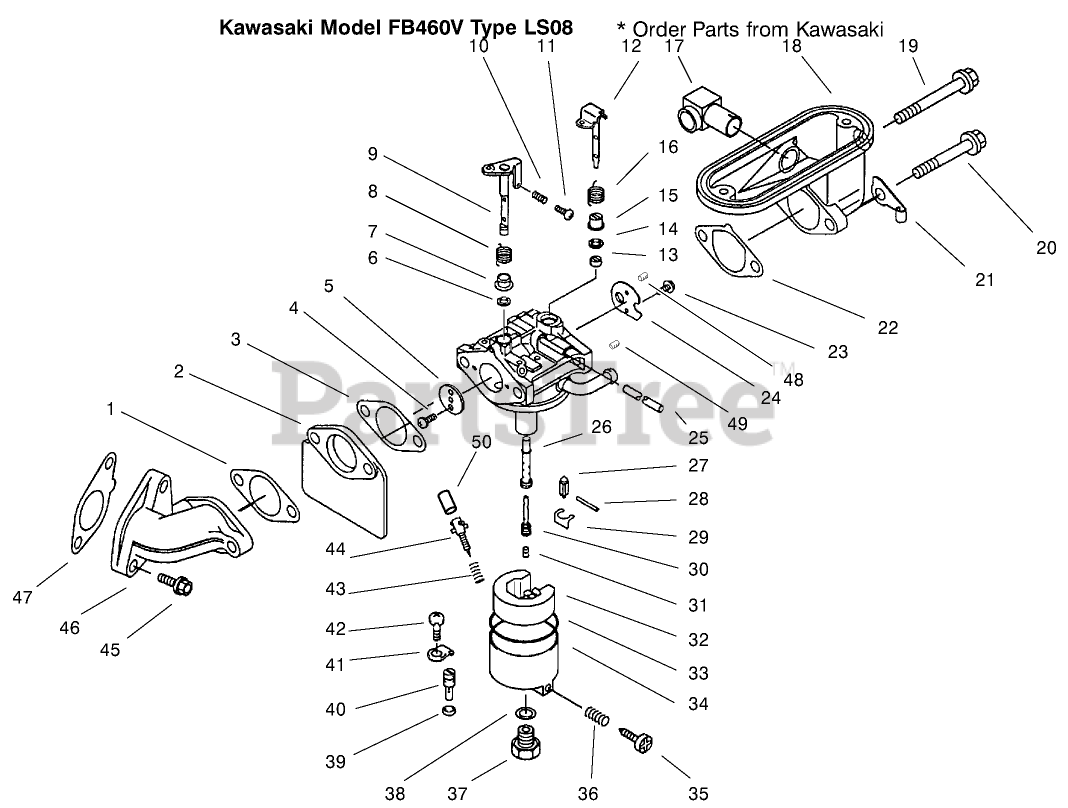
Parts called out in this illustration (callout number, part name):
1	Gasket
3	Gasket-Carburetor
4	Screw
5	Valve-Throttle #110
9	Shaft-Throttle
12	Shaft-Choke
18	Pipe-Intake
22	Gasket
23	Screw
24	Valve-Choke
25	Tube
26	Nozzle-Main
27	Valve-Float
30	Holder-Main Jet
31	Jet-Main
33	Gasket
34	Chamber-Float
35	Screw
44	Screw-Pilot Air
45	Bolt-Flanged (8X25)
46	Pipe-Intake
47	Gasket-Intake Pipe
48	Jet-Air #0.9
49	Jet-Air #1.4
